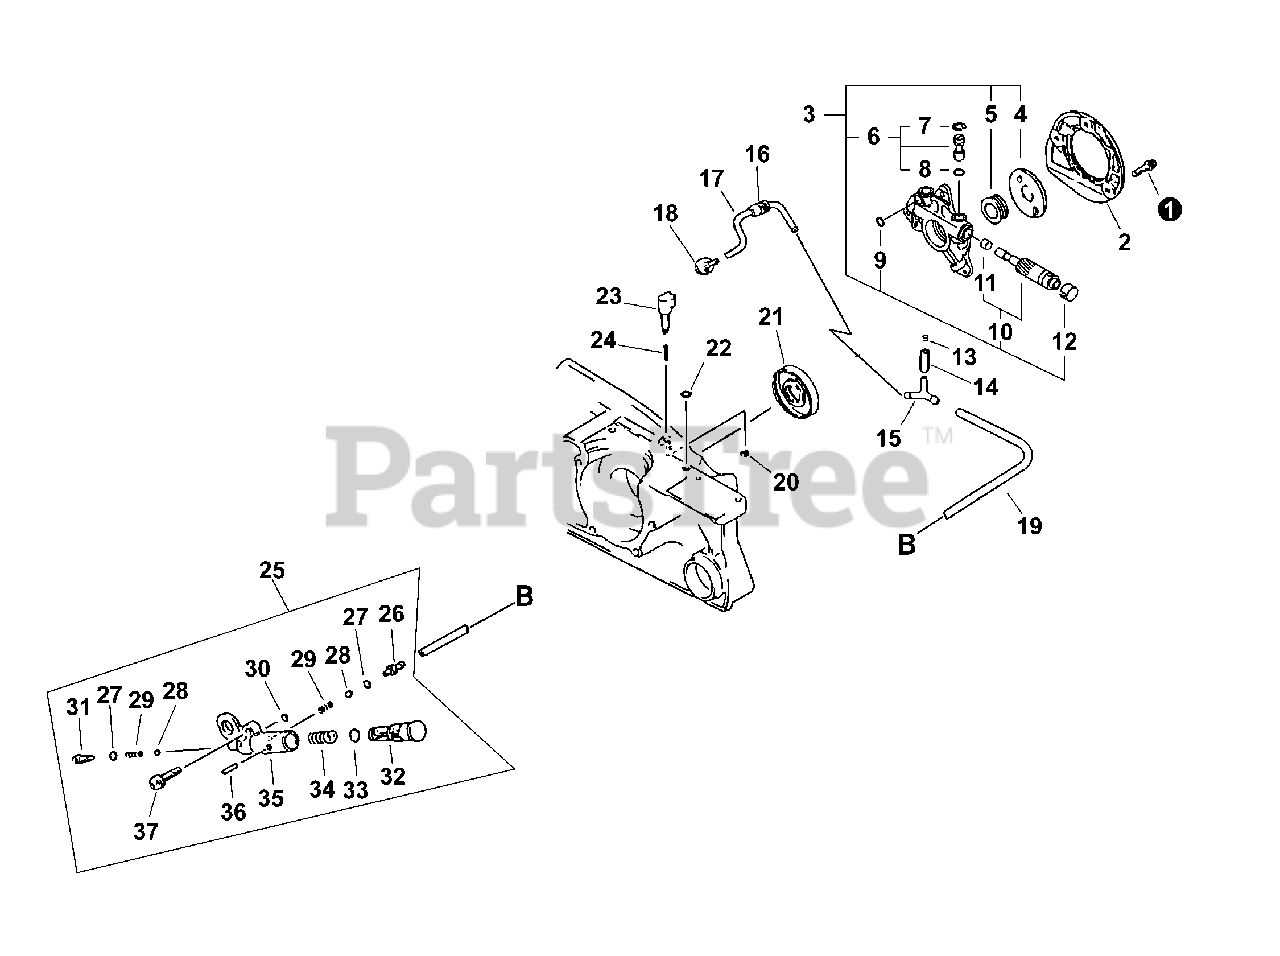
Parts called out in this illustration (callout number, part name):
1	BOLT 4×14
2	COVER, OIL PUMP - Gray
2	COVER, OIL PUMP - Orange
3	AUTO-OILER ASY
5	GEAR, WORM
6	CONTROL PIN ASY
9	O-RING 3
10	PLUNGER KIT
12	CAP, PLUNGER
13	CLIP
15	CONNECTOR, OIL PIPE
17	PIPE, OIL (INNER)
18	STRAINER, OIL
19	PIPE, OIL
20	E-RING 3
21	OIL SEAL
22	O-RING 3
23	ADJUSTER, AUTO OILER - Gray
23	ADJUSTER, AUTO OILER - Orange
25	OIL PUMP ASY
28	VALVE, BALL
29	SPRING, VALVE
30	O-RING 3
31	ADAPTOR, OIL PUMP
32	PISTON, OIL PUMP - Gray
32	PISTON, OIL PUMP - Orange
33	O-RING 7
35	BODY, OIL PUMP
36	PIN, SPRING 2×6
37	BOLT 5×20
